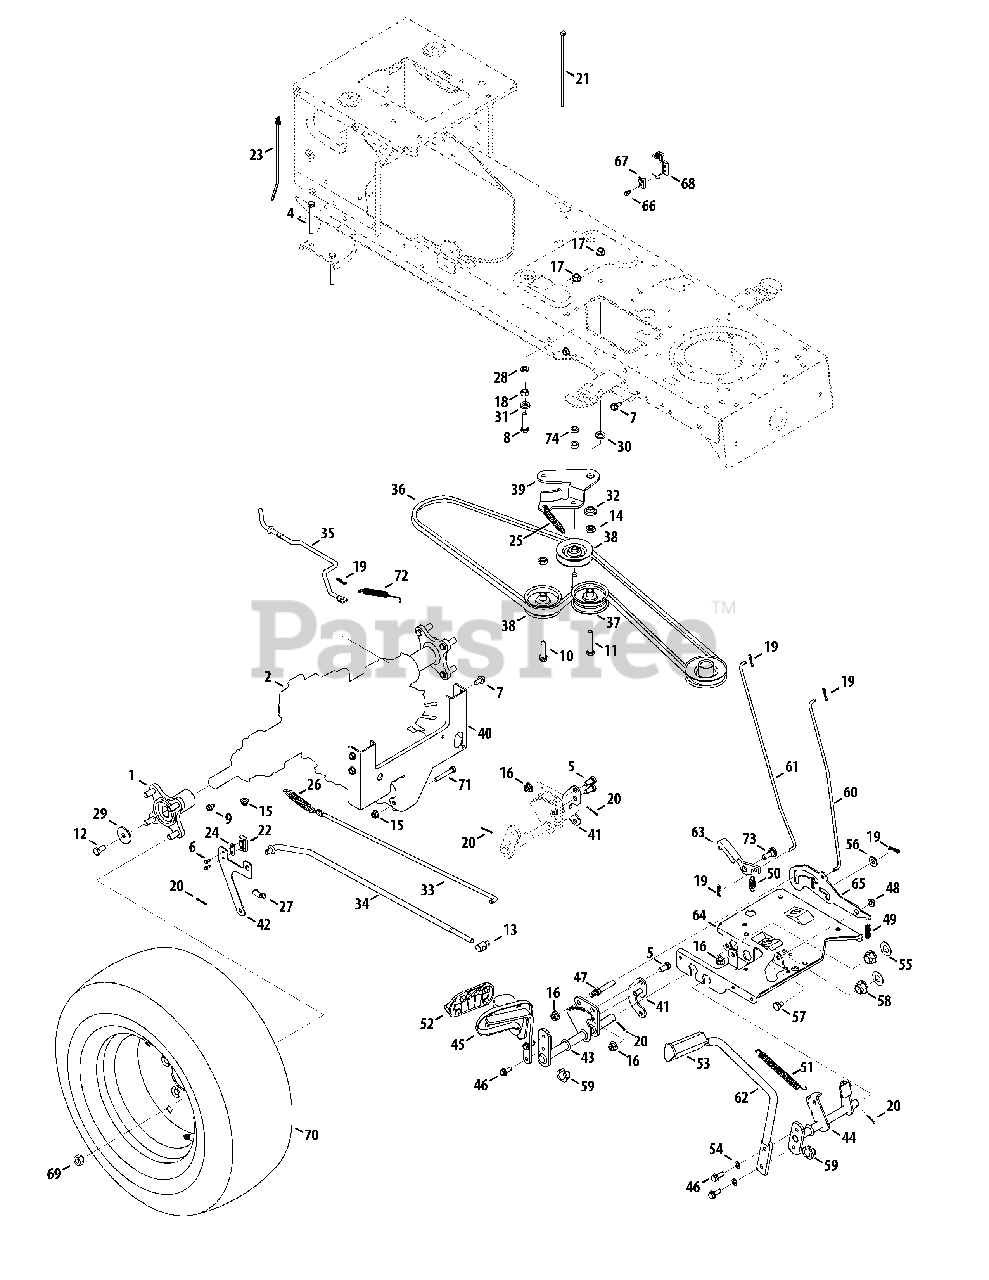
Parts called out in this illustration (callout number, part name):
1	Wheel Hub Assembly
2	Hydrostatic Transmission Ass'y
4	Hex Cap Scr. 5/16-18 x 3.0
5	Hex Cap Scr. 3/8-16 x .75
6	Screw #8-18 x .5
7	S-Tapp Scr 5/16-18 x .75
8	Hex Screw 3/8-16 x 1.50
9	Hex Wash S-Tapp Scr 1/4-20 x .50
10	Hex Cap Scr. 3/8-16 x 1.875
11	Hex Bolt 3/8-16 x 2.25" Lg.
12	Hex Cap Lock Screw 3/8-16 x .75 Gr. 5
13	Ferrule, 3/8-24
14	Hex Jam Nut 7/16-20
15	Flange Locknut 5/16-18 Gr. F, Ny lon
16	Flange Lock-Nut 3/8-16 Gr. F, Ny lon
17	Hex. Flanged L-Nut 3/8-16 Gr. F
18	Hex. Nut 3/8-16
19	Int. Cotter Pin .072 x 1.13" Lg.
20	Cotter Pin 3/32 dia x 1.00 Lg.
22	Short Spring Switch
23	Push-mount Cable tie
24	Insulator Nut Plate
25	Extension Spring .770 x 3.72" Lg.
26	Extension Spring .59 x 4.0
27	Extension Srping 3/8-1.44
28	L-Wash 3/8 ID
29	Flat Washer .39 ID x 1.5 OD x .135
30	Flat Washer .385 ID X 1.0 OD X .130
31	Flat Washer .406 x .875 x .059
32	Shoulder Spacer
33	Hydrostatic Brake Rod
34	Hydrostatic Control Rod
35	Hydrostic Bypass Rod
37	Flat Idler Pulley, 2.75
38	V-idler Pulley 3.06
39	Double Idler Bracket
40	Transmission Torque Bracket
41	Speed Control Bracket
42	Switch Actuator Bracket
43	Drive Control Ass'y
44	Brake Control Ass'y
45	Hy dro Pedal Ass'y
46	Self-Tap ping Scr. 5/16-18 x .75
47	in 3/8-16 x 2.68 Lg.
48	Hex Flange L-Nut 5/16-18
49	Compression Spring
50	Extension Spring, .50 OD x 1.41
51	Extension Spring, .50 Dia. x 6.37
52	Drive Pedal Pad
53	Brake Pedal Pad
54	L-Wash 5/16 ID
55	Flat Washer .640 ID x 1.24 OD x .06
56	Flat Washer .38 ID x .87 OD x .09
57	Shld. Scr .437 Dia x .162 Lg.
58	Hex Flange Bearing .630 ID
59	Hex Flanged Bearing .628 ID
60	Brake Lock Control Rod
61	Cruise Control Rod
64	Steering Support Bracket
65	Drive Lock out Bracket
66	Hex Scr. AB #10-16 x .50
67	Switch Plate
69	Lub Nut, 7/16-14
70	Wheel Assembly Complete, 23 x 10.5 x 12
71	Hex Hd Cap Scr. 5/16-18 x 2.0 Gr. 5
72	Extension Srping .50 OD x 5.0
73	Shoulder Screw .500 x .25
74	Spacer, .380 x .625 x .265
